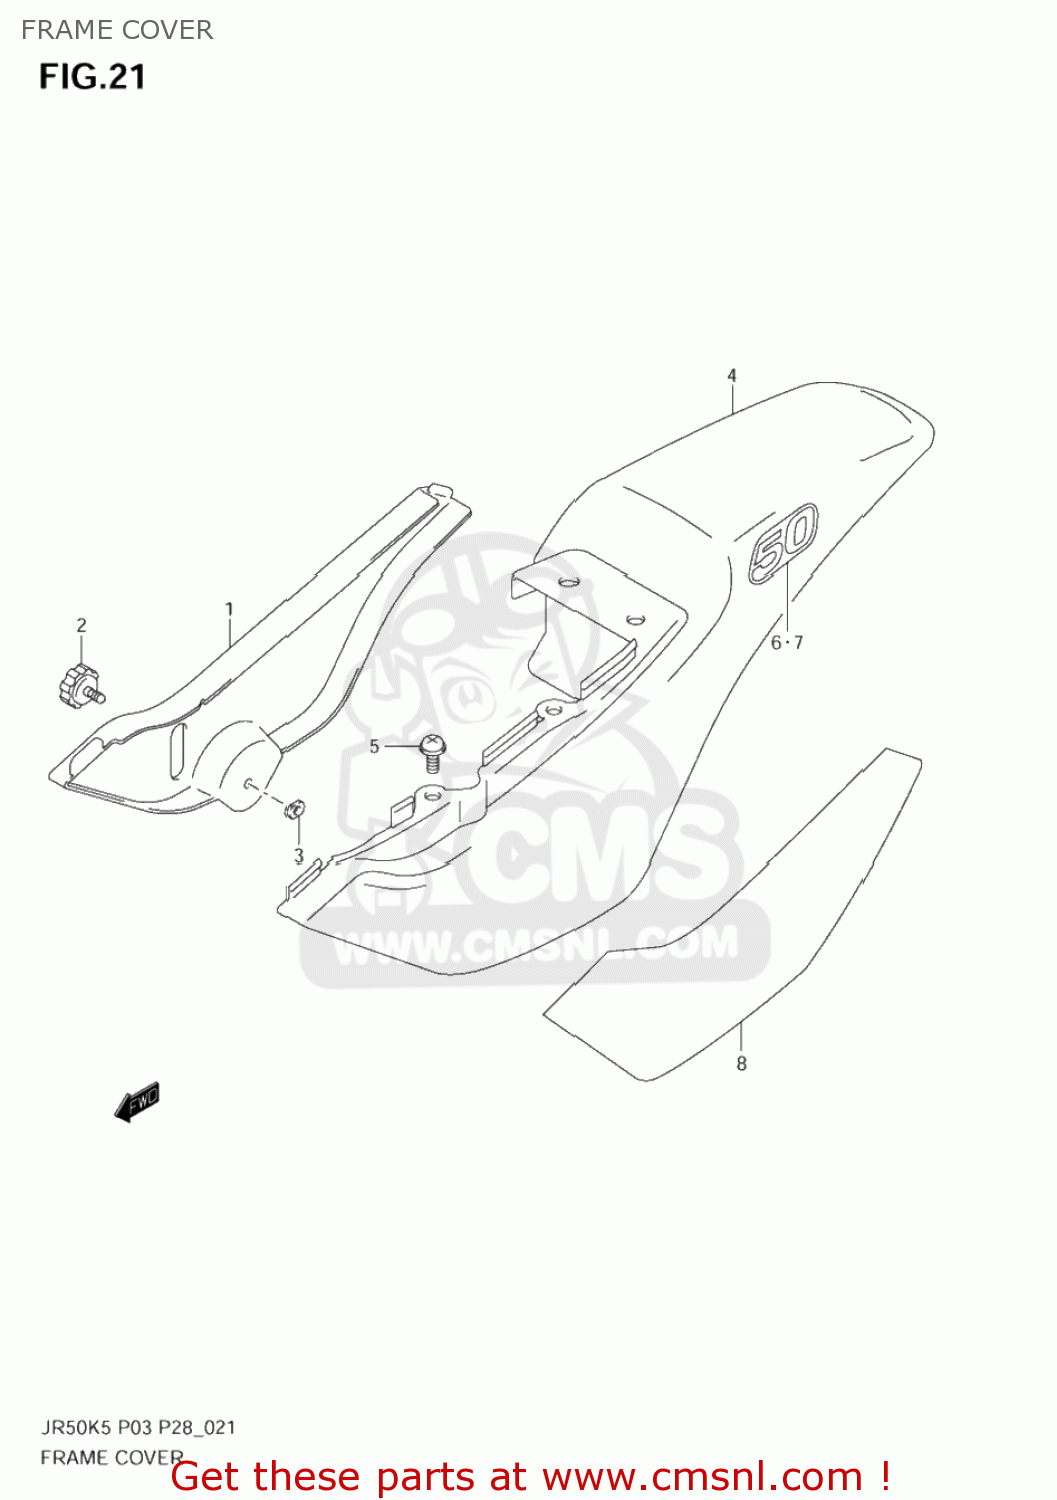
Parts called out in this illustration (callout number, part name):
1	COVER,FRAME,R(WHITE)
2	KNOB,FRAME COVER,R
3	NUT
4	COVER,FRAME,L(YELLOW)
5	SCREW(6X16)
6	EMBLEM,FRAME COVER,R
7	EMBLEM,FRAME COVER,L
8	TAPE,FRAME COVER,L
